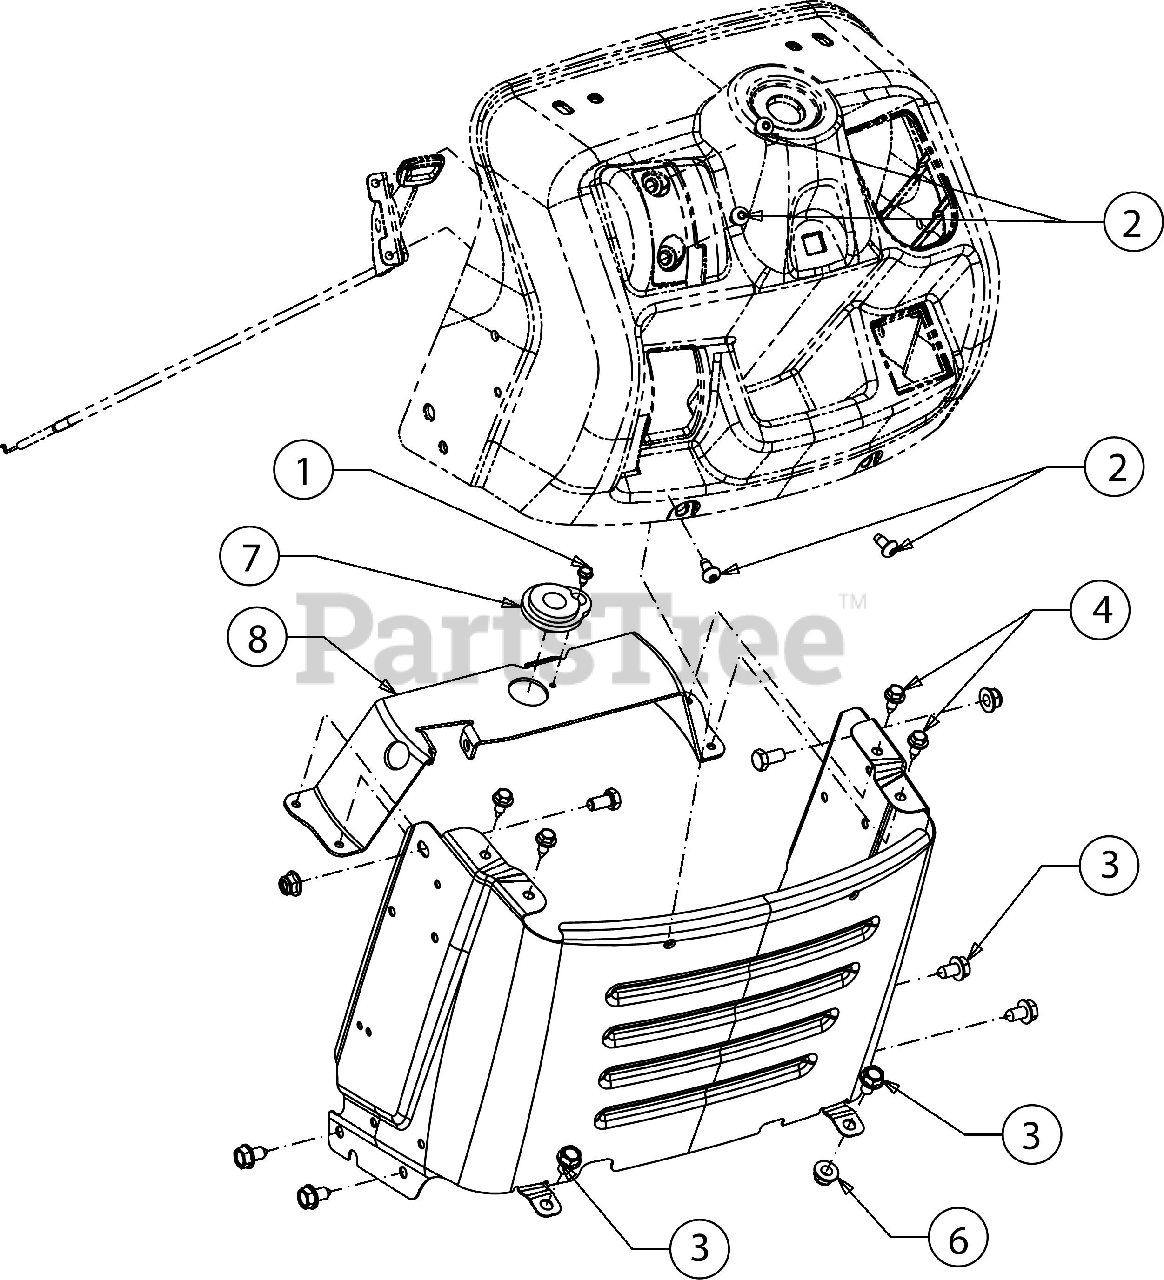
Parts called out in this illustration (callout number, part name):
1	HEX SCREW AB-TAP #10-16 X 0.500
2	SCREW 1/4-20 X .5
3	SCREW 5/16-18 X .625
4	SCREW 1/4-20X.625
5	SCREW 5/16-18X .625 GR5
6	FLANGE LOCK NUT 5/16-18
7	BEARING
8	STEERING SUPPORT BRACKET
9	LOWER DASH
